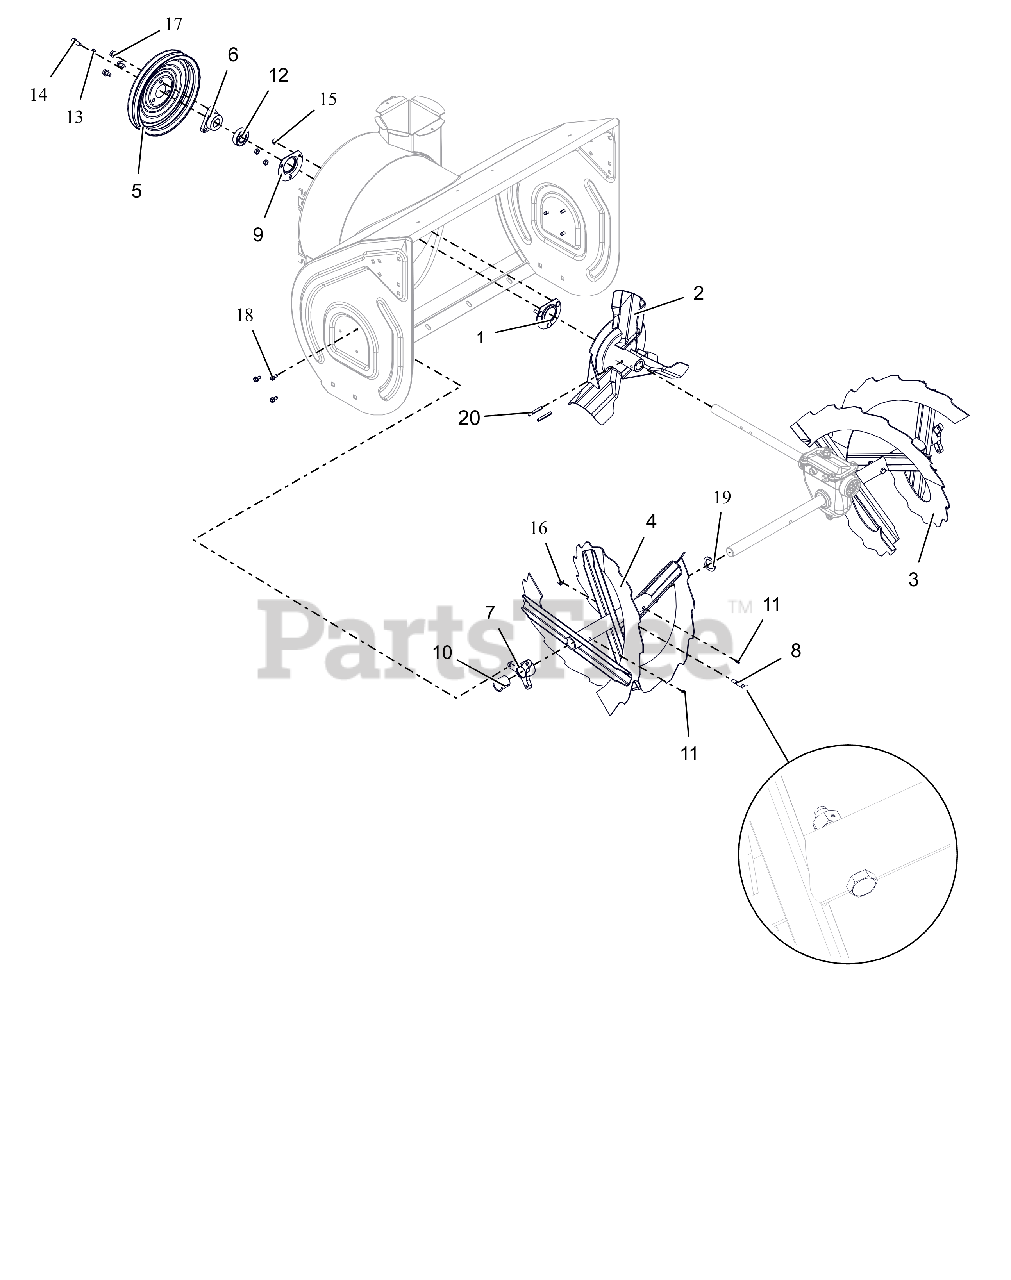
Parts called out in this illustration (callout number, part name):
1	BEARING FLANGE
2	IMPELLER, 3 BLADE-14"
3	RAKE, LH-28"(1 ID X 15.75 OD)
4	RAKE, RH-28"(1 ID X 15.75 OD)
5	PULLEY, SPIN FORM DUAL GROOVE
6	PULLEY HUB, D-BORE .87 PRO
7	BUSHING, RAKE SHAFT 1"
8	SHEAR BOLT SERVICE ASSEMBLY
9	BEARING FLANGE
10	BSHG-FLG SPLIT NYLINER 1.0" HP
11	ZERK,FITTING .25X.125 DRIVE IN
12	BRG-BALL .876X1.75X.50 RSTFP
13	WSHR, LK-HVY .312X.097 ZCC
14	BLT, HEX .31-24X.750 G5 ZCC
15	NUT,LK-CTR .25-20 GA ZCC
16	NUT,LK-CTR .31-18 GA ZCC
17	SCR,TAP .312-18X.50 HWH TR ZCC
18	SCR-TAP .25-20X.50 HWH ZCC
19	WSHR, FLT 1.010X1.505X.062 ZCC
20	PIN-ROLL .250X1.75
